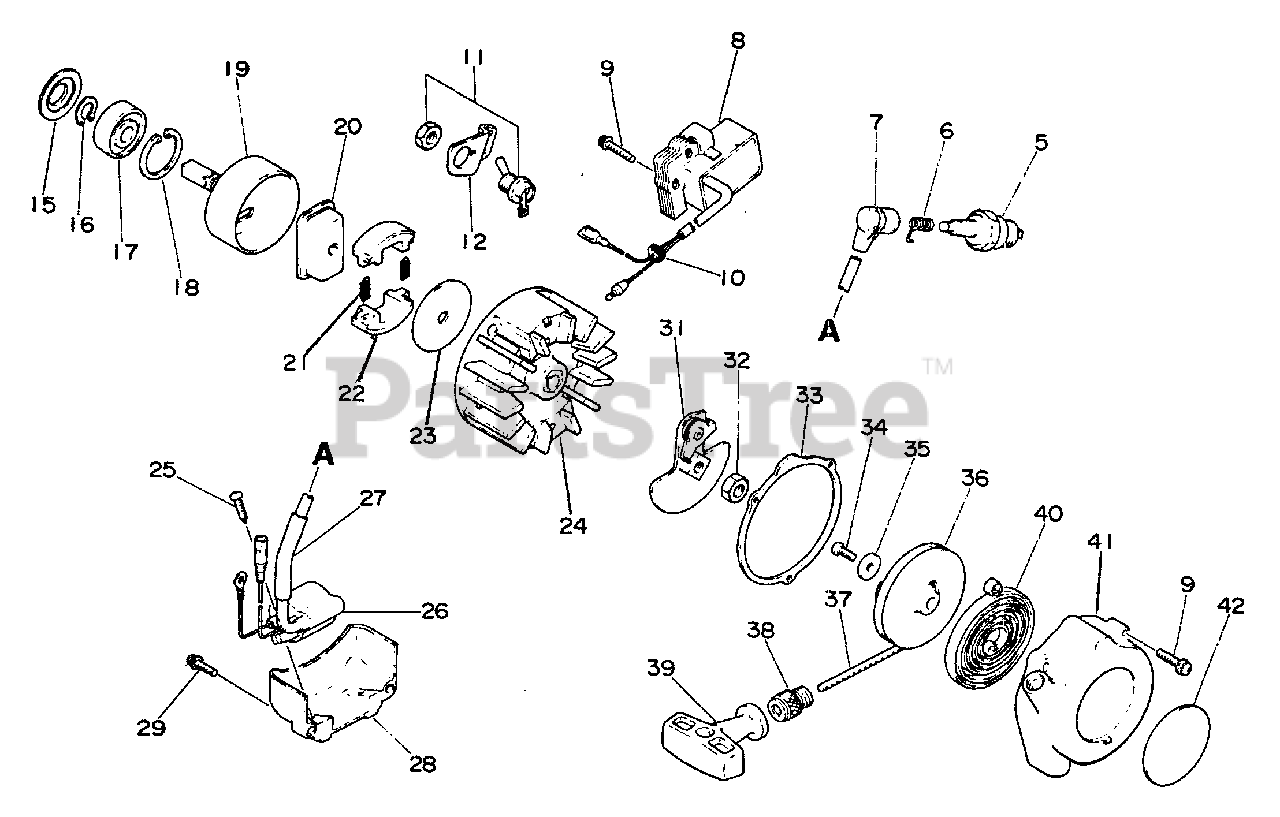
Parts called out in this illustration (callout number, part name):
5	SPARK PLUG - CJ8
6	TERMINAL, SPARK PLUG
7	CAP, SPARK PLUG
8	COIL, IGNITION
9	SCREW 4×20
11	SWITCH, IGNITION
12	BRACKET, SWITCH
15	STOPPER, PIPE
16	RING, RETAINING - 12
17	BEARING, BALL 6201
18	RING, SNAP Ø32
19	DRUM, CLUTCH
20	BOSS, CLUTCH
21	SPRING, CLUTCH
22	SHOE, CLUTCH
23	PLATE, CLUTCH
24	FLYWHEEL
25	SCREW - 4×16 -- TAPPING
26	COIL, IGNITION
27	PIPE
28	COVER
29	SCREW 4×14
31	PAWL ASSY, STARTER
32	NUT 8×1.25
33	GASKET, STARTER
34	SCREW - 4×10
35	WASHER 4.1×15.5×1T
36	REEL, ROPE
37	ROPE, STARTER 3.0×850
38	GUIDE, ROPE
39	GRIP, STARTER
40	SPRING, RECOIL
41	CASE, STARTER
42	LABEL - ECHO
